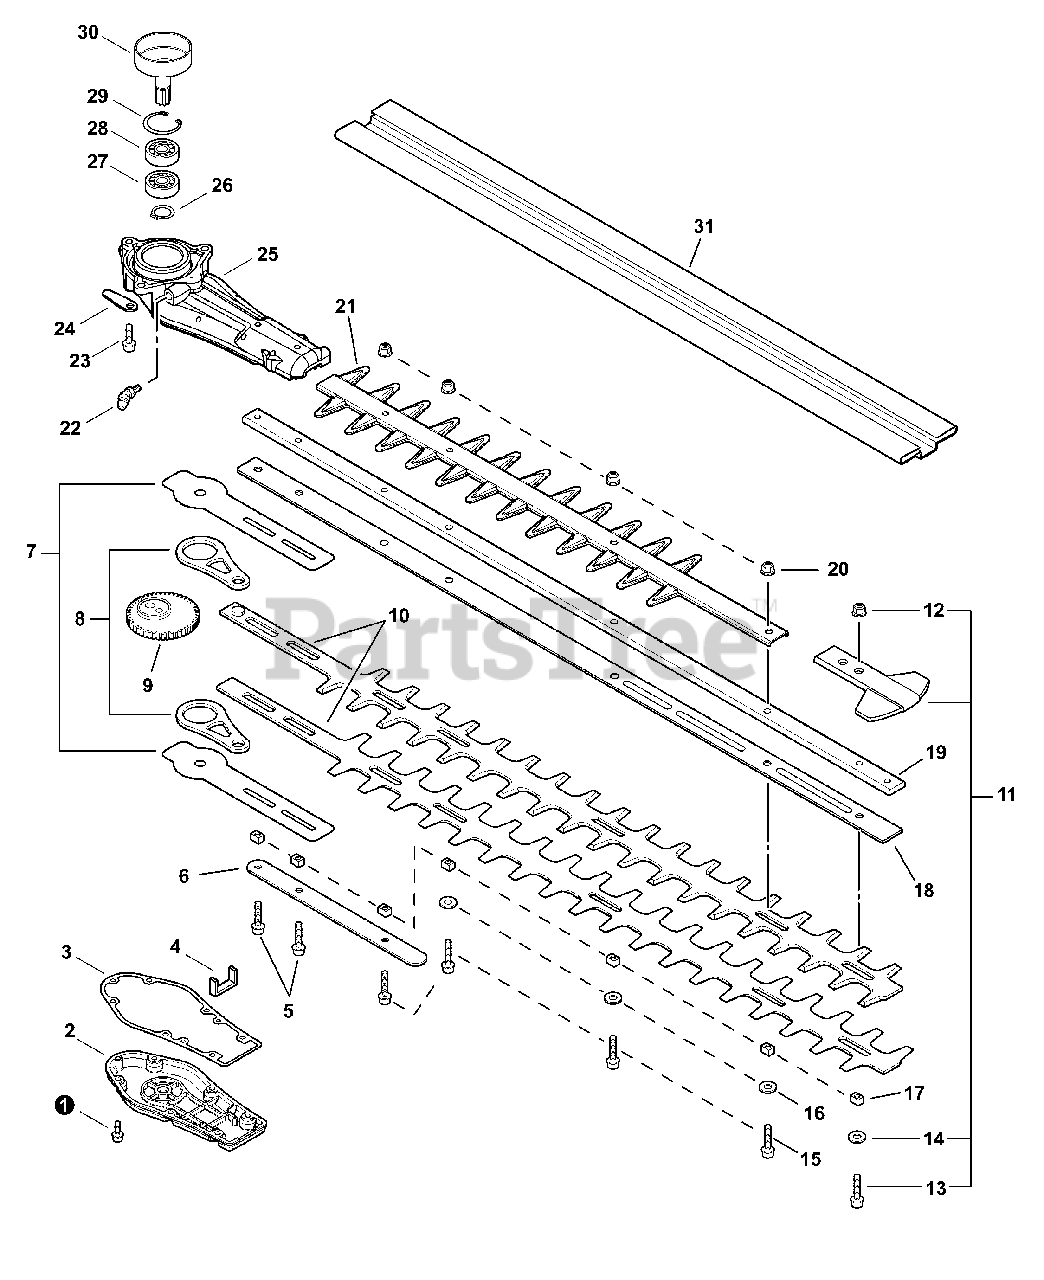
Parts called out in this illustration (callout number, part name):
1	BOLT 4×16
2	COVER, GEAR CASE
3	GASKET, GEAR CASE
5	BOLT 5×25
6	PLATE, EYE
7	PLATE, EYE
8	ROD, CONNECTING
9	GEAR, SPUR
11	TIP GUARD KIT
12	NUT, FLANGE M5
13	BOLT, FLANGE 5×22
14	WASHER 5
15	BOLT, FLANGE 5×22
16	WASHER 5
17	GUIDE, BLADE 5
18	SUPPORT, BLADE
19	SUPPORT, BLADE
20	NUT, FLANGE M5
21	GUARD, CUTTER BLADE
22	FITTING, GREASE
23	BOLT, FLANGE 6×20
25	CASE, GEAR
26	RING, SNAP 14
27	BEARING, BALL 6202
28	BEARING, BALL 6202 DDU
29	RING, SNAP 35
30	DRUM, CLUTCH
31	SCABBARD
